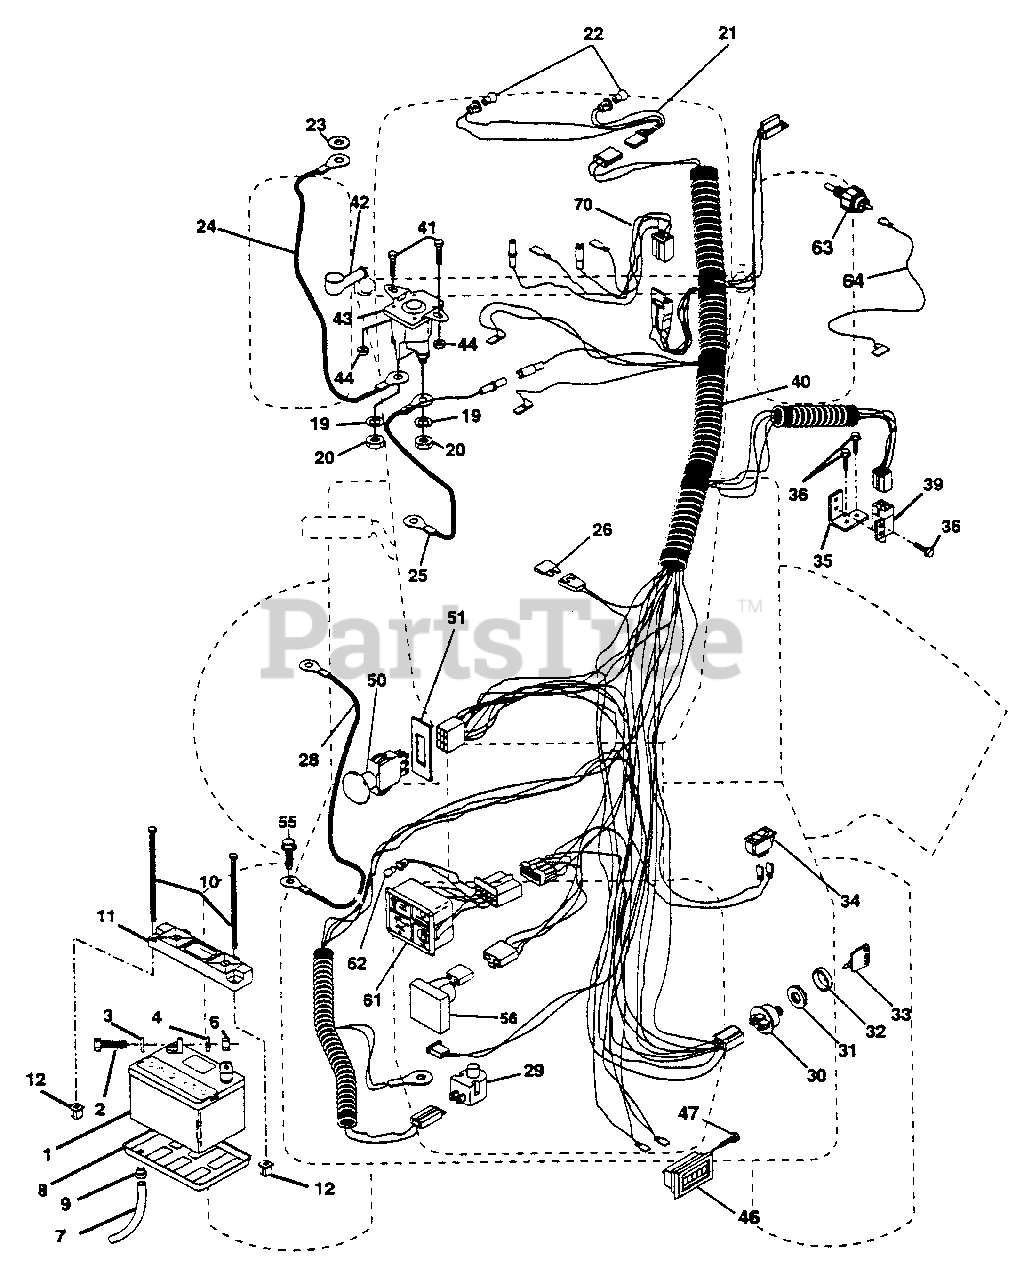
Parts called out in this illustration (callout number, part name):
1	Battery
2	Bolt, Hex Head 1/4-20 x 3/4
3	Washer 9/32 x 5/8 x 16 Gauge
4	Washer, Lock 1/4
6	Nut, Hex 1/4-20
7	Tube, Tray, Battery
8	Tray, Battery
9	Clamp, Hose
10	Bolt, BTR FRT 1/4-20 x 7-1/2 Zinc
11	Holddown Battery Dash Mount
12	Nut, Push Nylon Battery FRT 1/4"
19	Washer, Lock 1/4
20	Nut, Hex, Jam 1/4-20
21	Harness, Socket, Light
22	Bulb, Light
24	Cable, Starter, 6 Ga W/16 Wire 22" Red
25	Cable, Battery
28	Cable, Battery
29	Switch, Plunger
30	Switch, Ignition
31	Nut, Ignition
32	Cover, Switch, Ignition
33	Key, Molded
34	Switch, Light
35	Bracket Switch Interlock
36	Screw, Hex Tap #10-24 UNC
39	Switch, Interlock (4 Terminal)
40	Harness, Ignition
41	Bolt, Hex 1/4-20 x 1/2 Grade 5
42	Cover, Terminal
43	Solenoid
44	Nut, Lock W/Insert 1/4-20 UNC
46	Meter, Hour
47	Screw #10-24 x 1/2
49	Washer Lock Internal Tooth 5/8
50	Switch, P.T.O.
51	Ring, Retainer, Pto
55	Screw Thdrol 5/16-18 x 1/2 TYT
56	Sensor, Low Voltage
61	Package, Light
62	Bulb, Light Package
63	Switch, Engine Oil Pressure
64	Wire Lead Sentry Oil Vanguard
70	Harness, Engine
